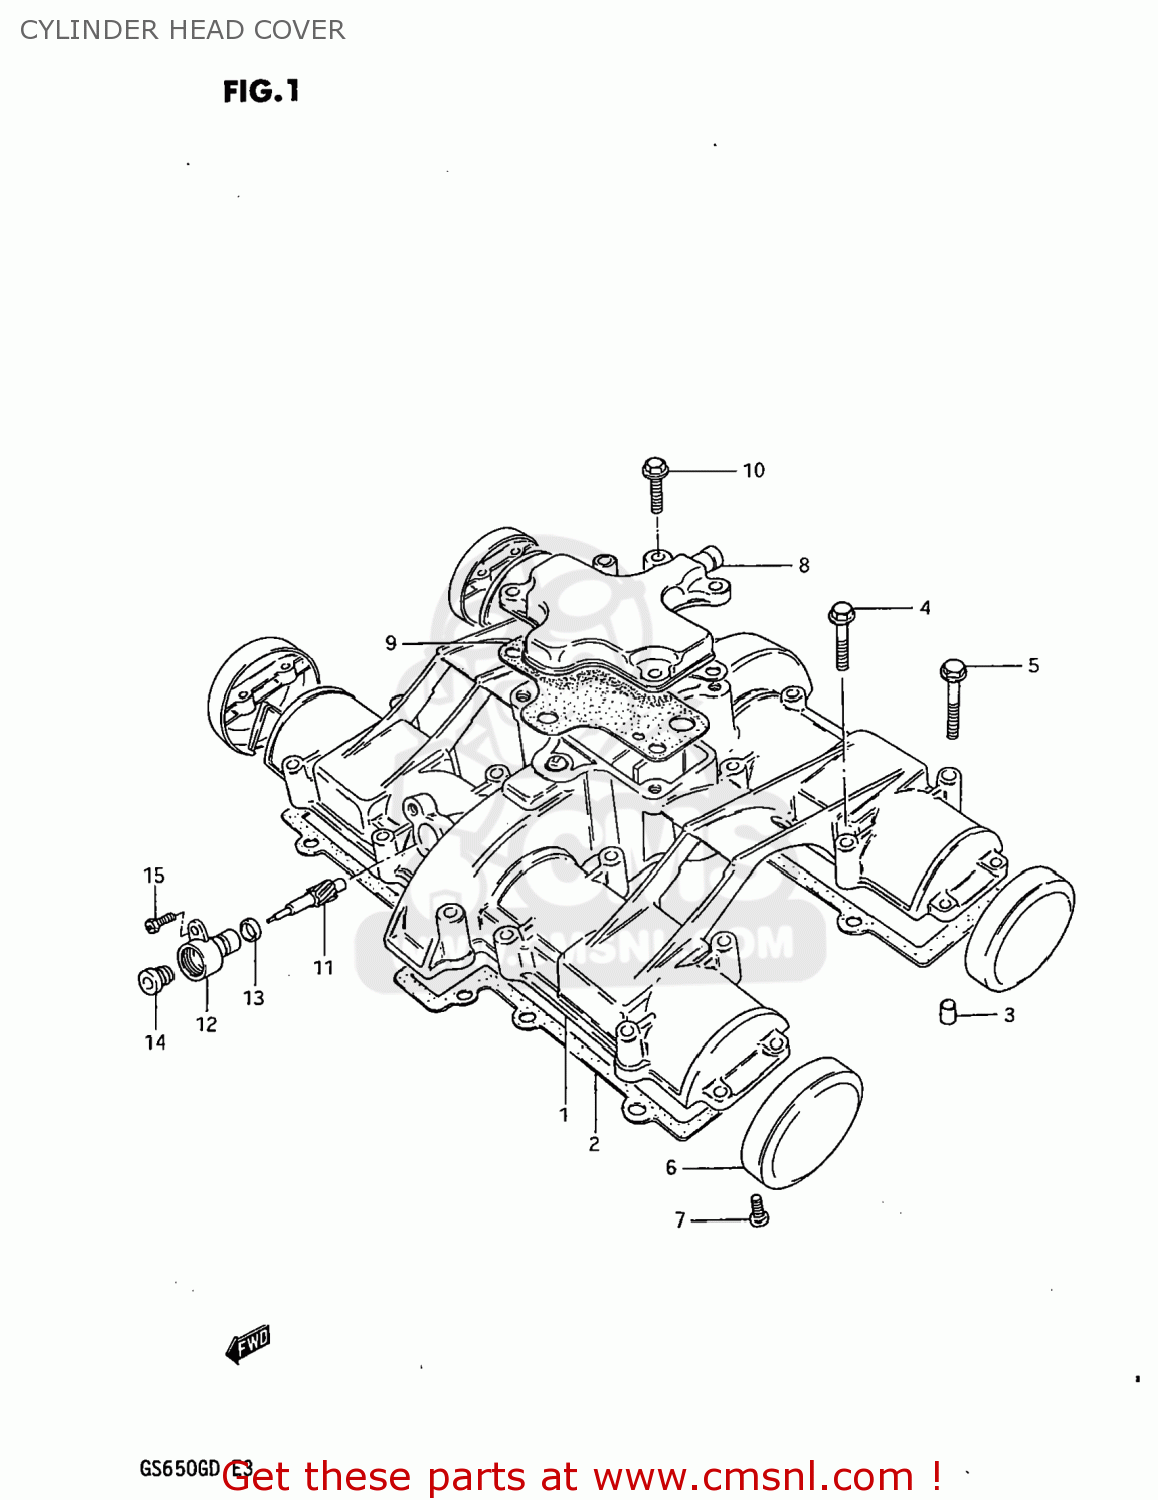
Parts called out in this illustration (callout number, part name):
1	COVER,CYLINDER HEAD
2	GASKET,CYLINDER HEAD COVER (MCA)
3	PIN(6.2X8X11)
4	BOLT
5	BOLT,UNDER
6	CAP,CYLINDER HEAD COVER
7	SCREW
8	COVER,BREATHER
9	GASKET (MCA)
10	BOLT,REAR
11	GEAR,TACHOMETER DRIVEN
12	SLEEVE,TACHOMETER DRIVE GEAR
13	SEAL,TACHOMETER DRIVEN
14	SEAL,OIL(5X12X8)
15	SCREW(5X12)
